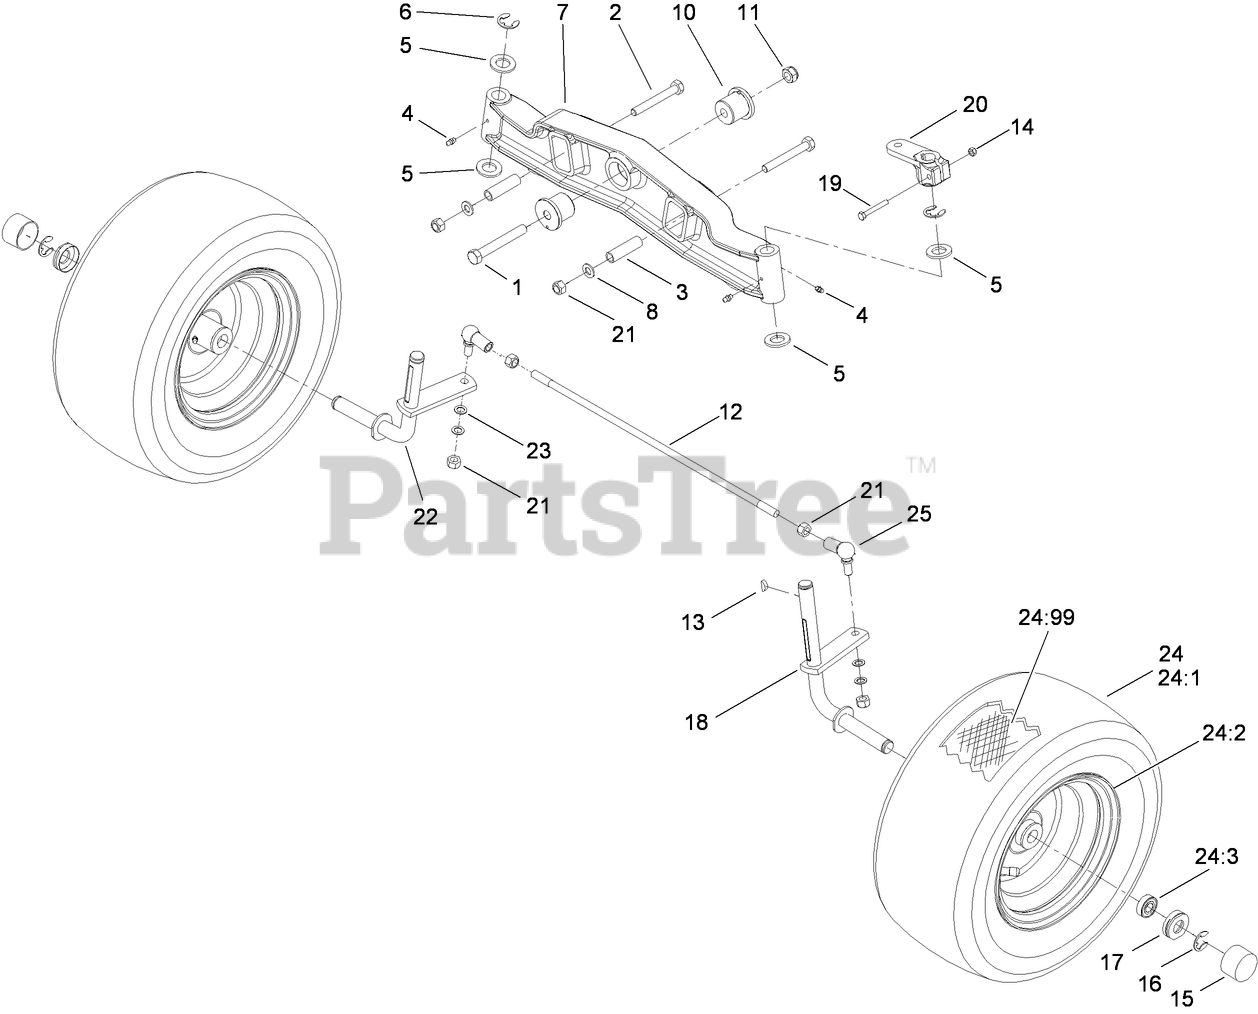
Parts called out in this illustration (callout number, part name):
1	SCREW-HH
2	SCREW-HH
3	SPACER
4	FITTING-GREASE
5	WASHER-FLAT
6	CLIP-SPRING
7	AXLE-FRONT
8	WASHER-FLAT
10	BUSHING-AXLE, FRONT
11	NUT-LOCKING, SELF
12	ROD-TIE, FRONT AXLE
13	KEY-WOODRUFF
14	NUT-LOCK
15	CAP-HUB
16	CLIP-SPRING
17	RETAINER-CAP, HUB
18	SPINDLE-FRONT, LEFT
19	SCREW-HH
20	LEVER-SPINDLE, STEERING
21	NUT-LOCK, NI
22	SPINDLE-FRONT, RIGHT
23	Washer
24	WHEEL ASM
24:2	RIM-FRONT
24:3	BEARING-WHEEL
24:99	TUBE-INNER
25	JOINT-BALL, ANGLE
